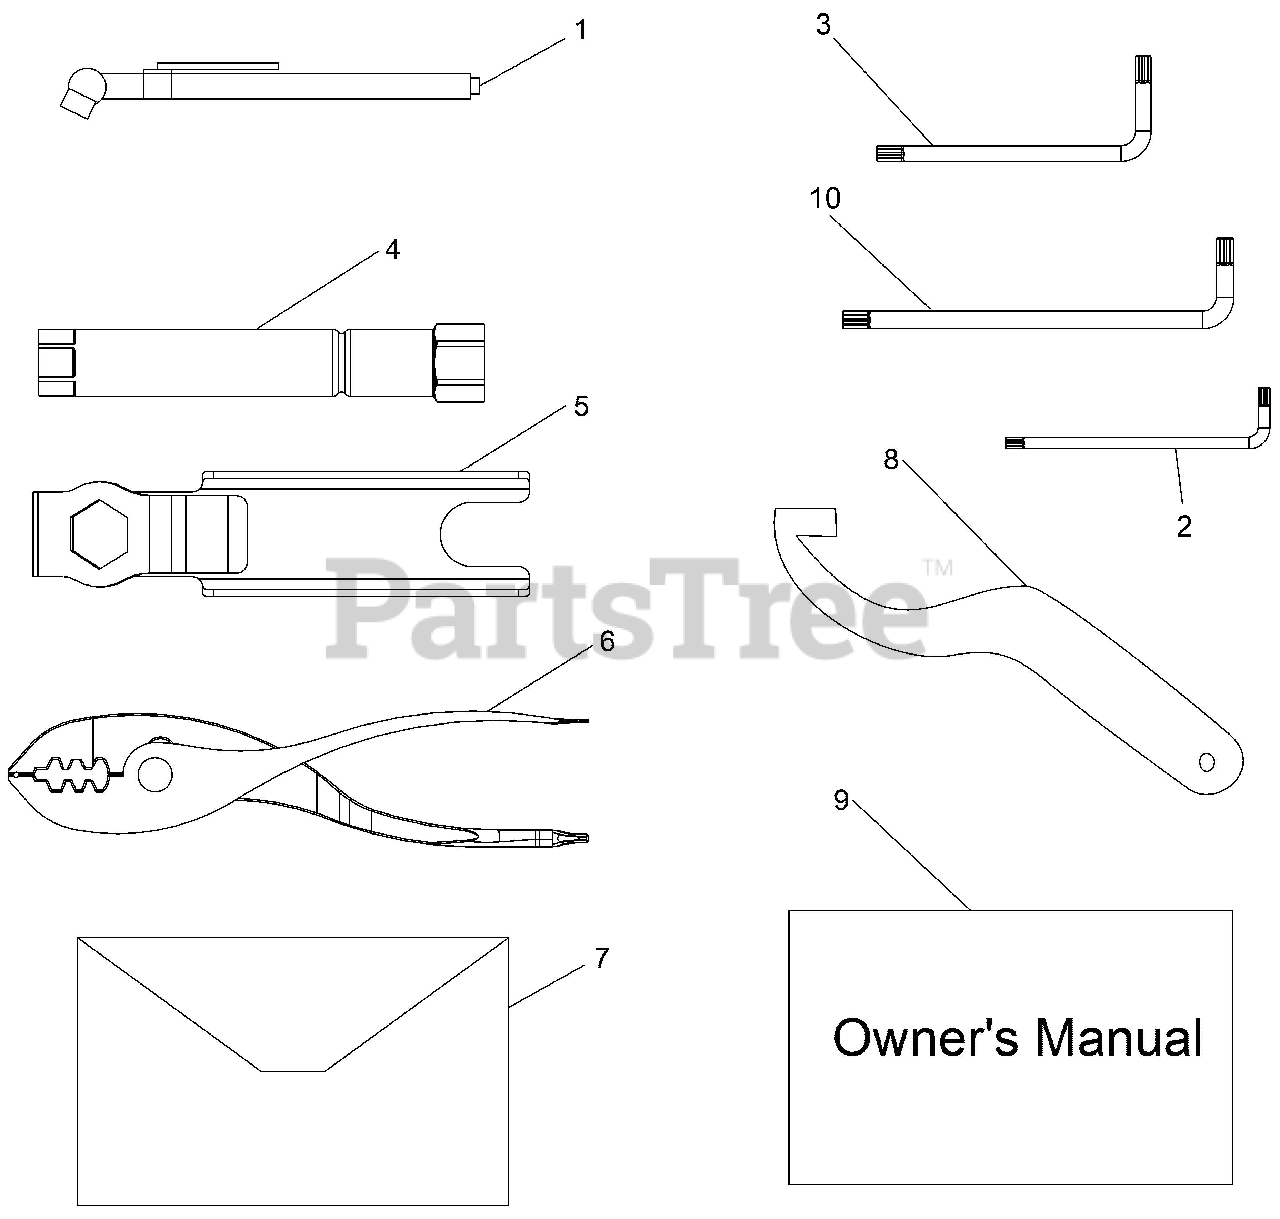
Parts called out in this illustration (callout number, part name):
1	GAUGE-TIRE PRESSURE,30 PSI
2	WRENCH-TORX,T-25
3	WRENCH-TORX,T-27
4	SOCKET, SPARK PLUG
5	HANDLE, SPARK PLUG
6	PLIERS-COMBO, #2 ASSEMBLY
7	POUCH,TOOLKIT,9"
8	WRENCH-SPANNER, CAM
9	MANUAL,GAS OWNERS -ENGLISH
10	WRENCH-TORX,T-40
